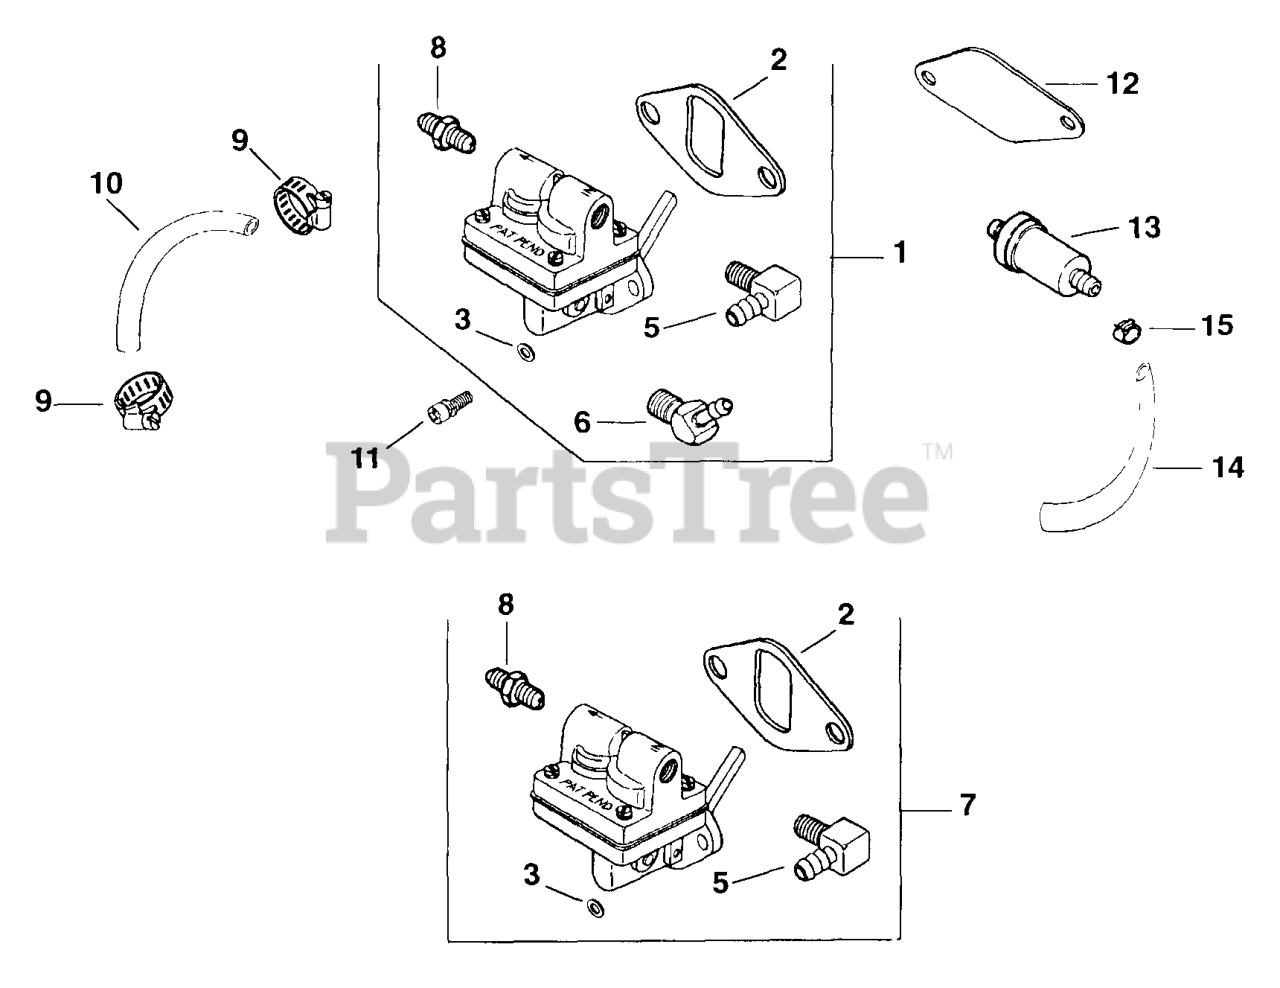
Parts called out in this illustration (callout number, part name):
3	WASHER, FLAT 1/4" (O.D. 1/2")
5	CONNECTOR, 90 DEG. HOSE
6	CONNECTOR, 45 DEG.
9	CLAMP, HOSE 1/2" USE 25 237 14-S
10	LINE - DISCONTINUED
